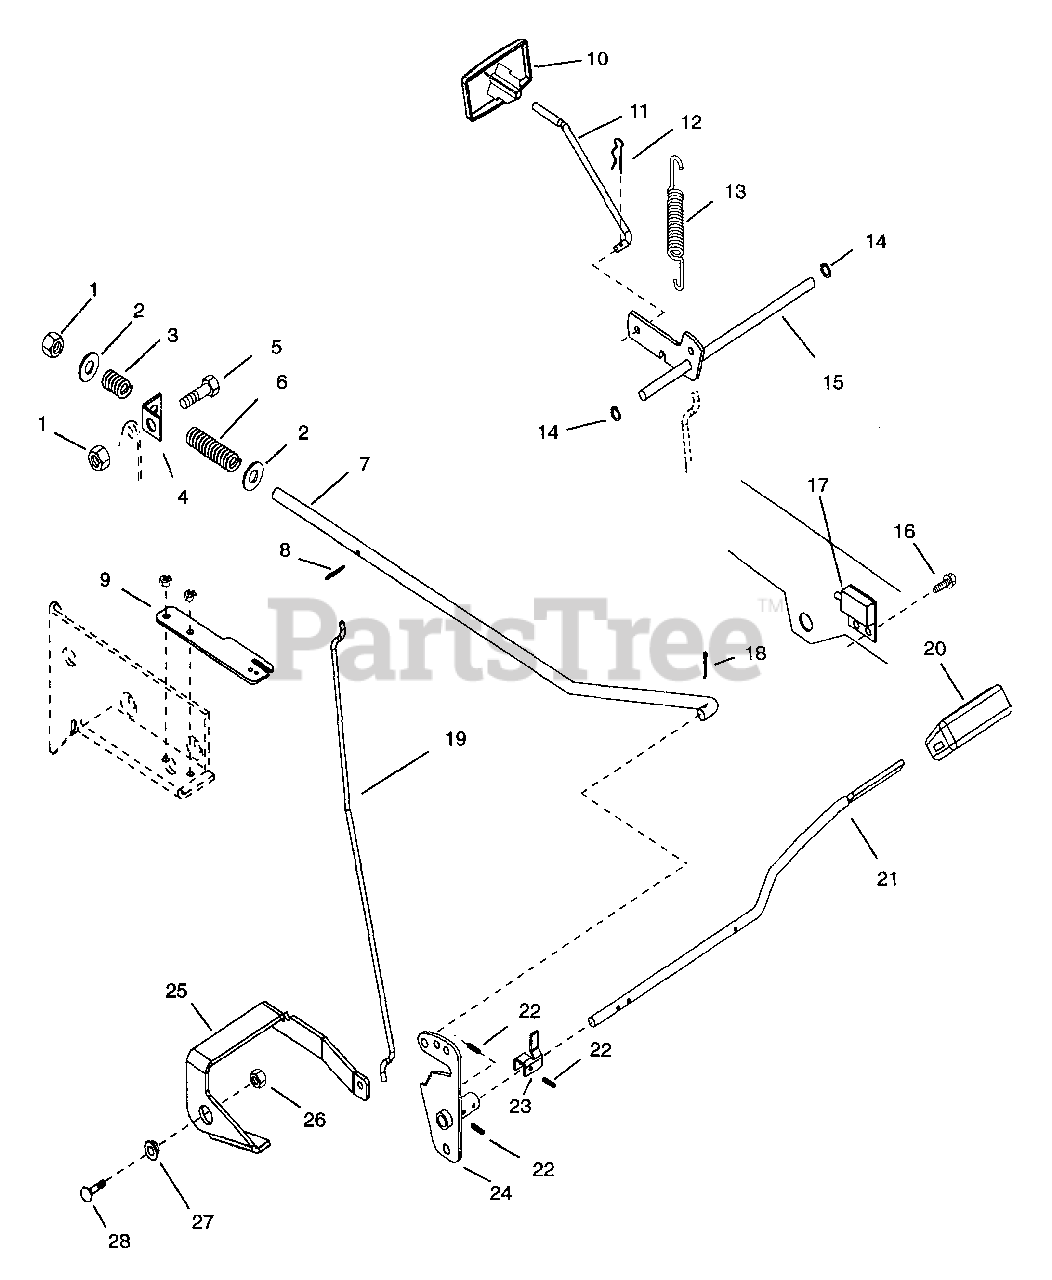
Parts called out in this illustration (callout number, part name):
1	NUT-LK-CTR .375-16 GR A PL
2	WSHR-FL-STL.406X.812X.065PL
3	SG-COMP .125X.78X1.00 YWZ
4	BRACKET
5	BLT-HEX .38-16X.75 PL GR5
6	SG-COMP .048X.59X2.06 WLD9
7	ROD - BRAKE
8	PIN-ROLL .125X.75
9	BRAKE GUIDE
10	KNOB- PARK BRAKE
11	ROD, PARKING BRAKE
12	PIN-HAIR INT .06X.18X.77
13	SG-TENS .051X.60X2.25 WLD 7.0
14	RG-RTNG-EXT .250X.010
15	BELLCRANK-PARKING BRAKE
16	SCR-TAP 12-24X.50 HWH PL TR
17	SWITCH- SINGLE POLE N.O.
18	PIN-COTR .09X.75 PL
19	ROD, PARKING BRAKE
20	COVER - PEDAL - BRAKE
21	PEDAL - BRAKE
22	PIN-GRV .188X1.25 TP A
23	LEVER - BRAKE SWITCH
24	ARM & HUB - BRAKE
25	LEVER, PARKING BRAKE
26	NUT-LK .312-18 GR A PL
27	BSHG, FLG .325X.499X.26X.88
28	BLT-RDHDSQNK.31-18X.75GR5SHTPL
